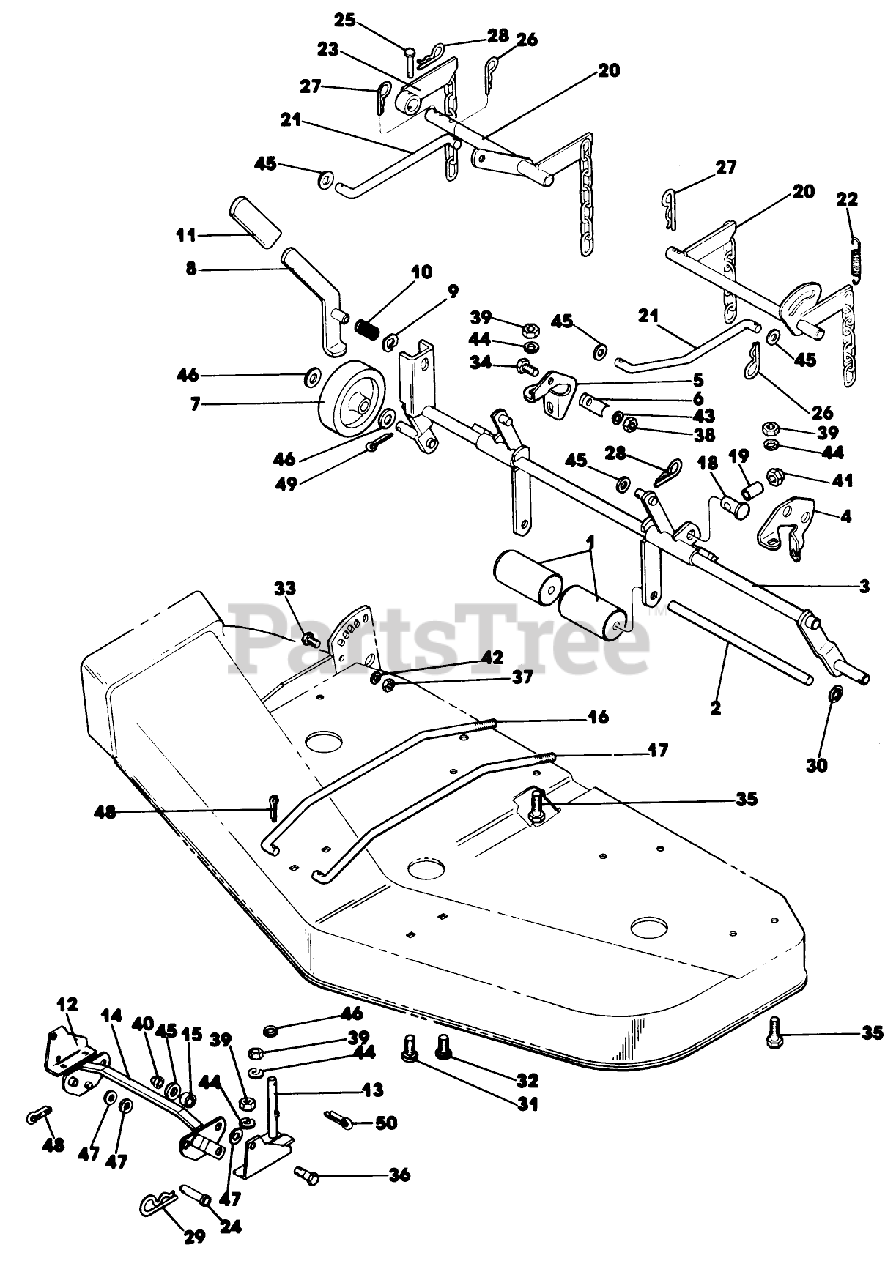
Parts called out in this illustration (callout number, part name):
20	Bellcrank Assembly (Yard Tractor)
21	Link-Mower Lift (Hydro)
43	Lock Washer 5/16 Plated
